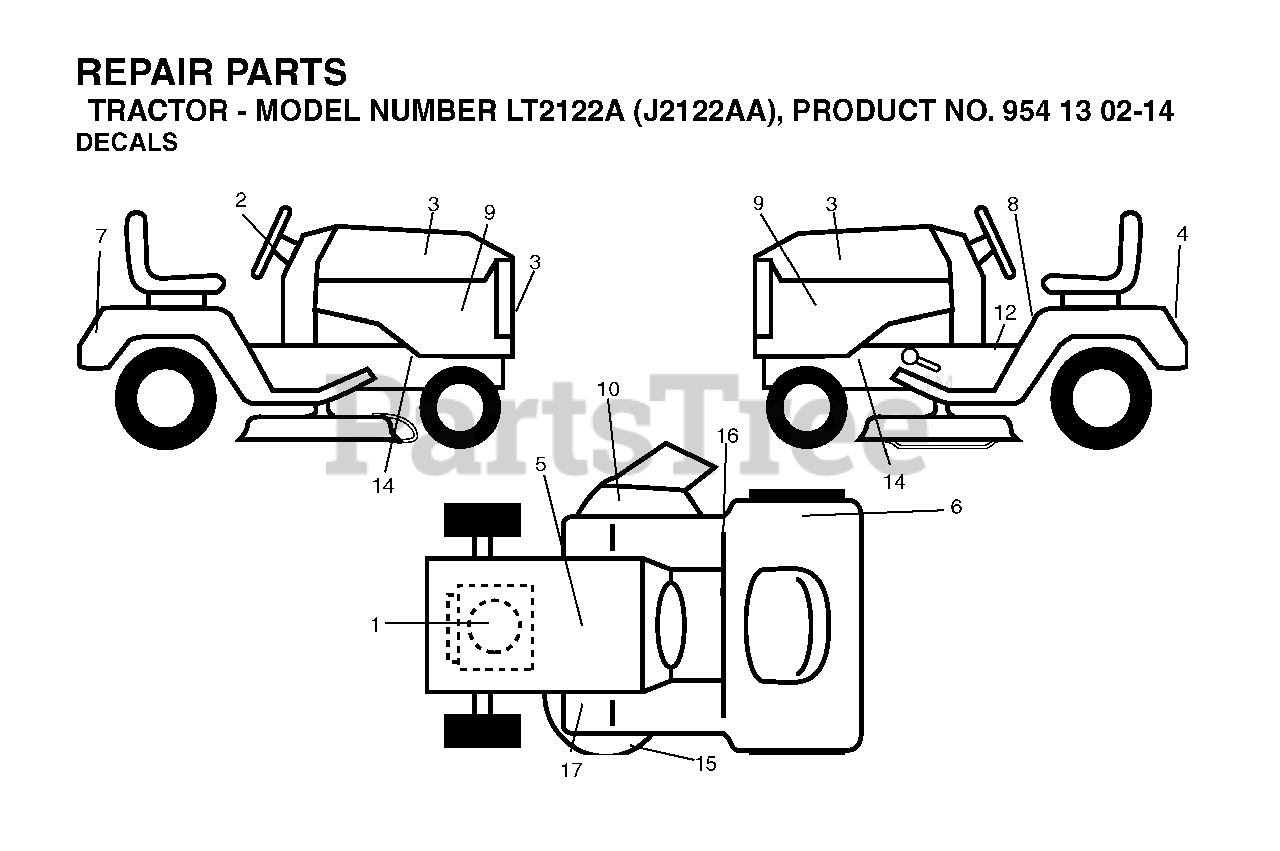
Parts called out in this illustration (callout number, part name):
5	DECAL BTRY SYMBOLS
6	DECAL.FENDER
8	DECAL READ OWNER'S MAN SYMS
10	DECAL.INTERNATIONL.CUTFINGER
12	DECAL PARK BRAKE
15	DECAL V-BELT SCHEMATIC
